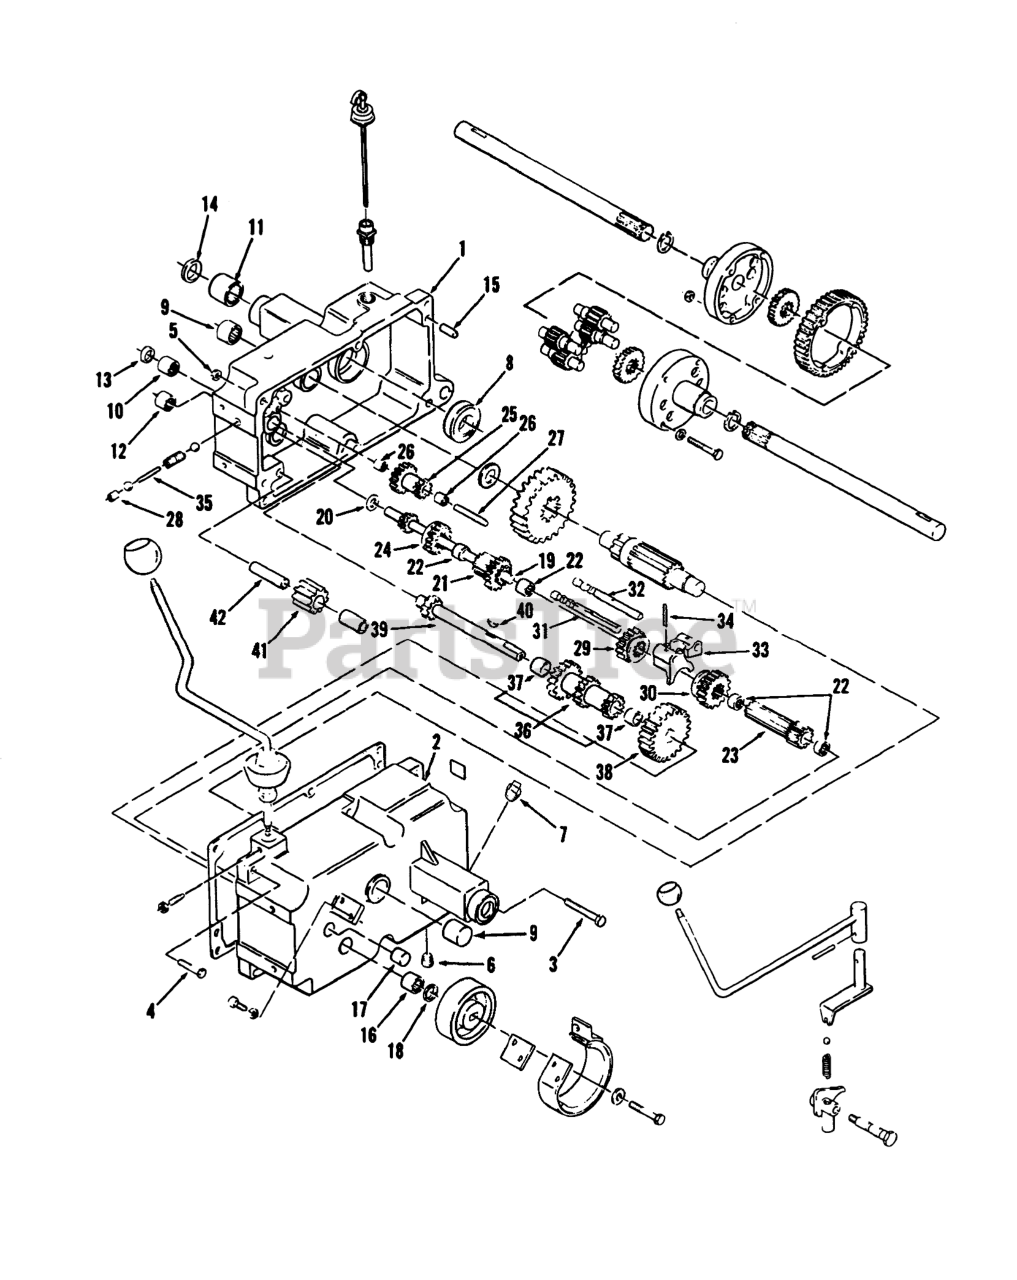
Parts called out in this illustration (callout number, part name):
1	Case Trans RH
2	Case Trans LH
3	SCREW-HH
4	SCREW-HH
5	NUT-LOCK, NI
7	PLUG-PIPE, SQH
8	BEARING-BALL
9	BEARING-NEEDLE
10	BEARING-NEEDLE
11	BEARING
12	BEARING-NEEDLE
13	SEAL-OIL
14	SEAL-OIL
15	PIN-DOWEL
16	BEARING-NEEDLE
17	Bearing Needle
18	SEAL-OIL
19	SHAFT-INPUT
20	WASHER-THR
21	GEAR
22	BEARING-NEEDLE
23	GEAR
24	GEAR-SLIDING
25	Gear
26	BEARING-NEEDLE
27	GEAR-SHAFT REDUCTION
28	CUP-PLUG
29	GEAR-HI AND 2ND
30	GEAR-LOW AND REVERSE
31	RAIL-SHIFT
32	RAIL-REAR SHIFT
33	FORK-SHIFT
34	PIN-ROLL
35	PIN-SHIFT
